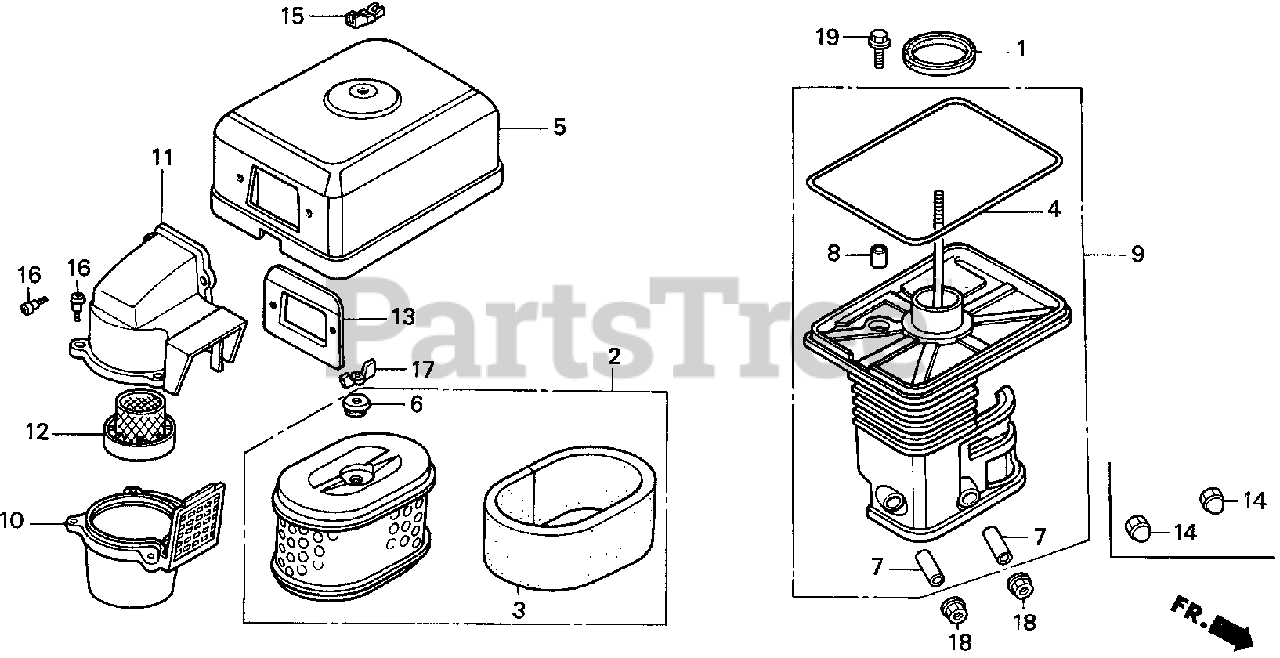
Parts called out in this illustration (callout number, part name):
1	GASKET, ELBOW
2	ELEMENT, AIR CLEANER (DUAL)
3	FILTER (OUTER)
4	GASKET, AIR CLEANER COVER
5	COVER, AIR CLEANER (DUAL)
6	GROMMET, AIR CLEANER
7	COLLAR, AIR CLEANER
8	COLLAR B, AIR CLEANER
9	ELBOW, AIR CLEANER
10	CASE, PRE AIR CLEANER
11	CAP, PRE AIR CLEANER
12	GUIDE, PRE AIR CLEANER
13	PLATE, PRE AIR CLEANER
14	NUT, CAP (6MM)
15	WINGNUT, AIR CLEANER COVER
15	WINGNUT (6MM)
15	WINGNUT, TOOL BOX SETTING
16	BOLT, MUDGUARD
17	WINGNUT, TOOL BOX SETTING
18	NUT, FLANGE (6MM)
19	BOLT, FLANGE (6X20)
